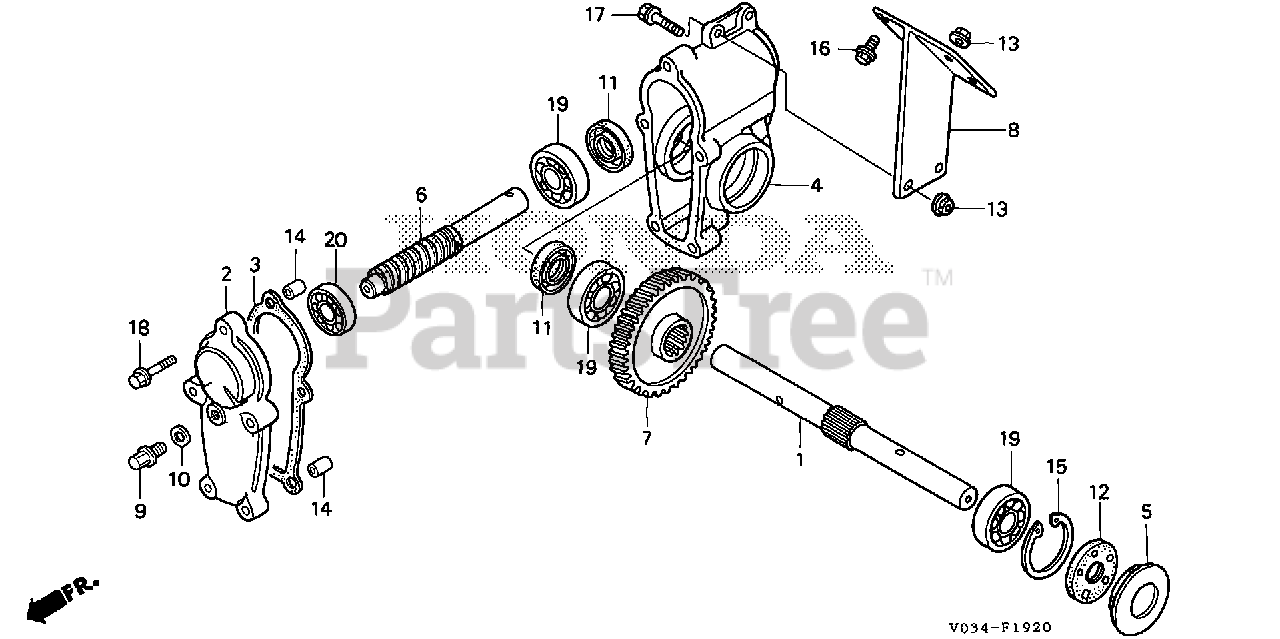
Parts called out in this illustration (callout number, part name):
1	SHAFT, AUGER
2	COVER, AUGER TRANSMISSION
3	GASKET, AUGER TRANSMISSION
4	CASE, AUGER TRANSMISSION
5	CAP, AUGER CASE
6	GEAR, DRIVE
7	GEAR, DRIVEN (55T)
8	BRACKET, AUGER HOUSING
9	BOLT, DRAIN PLUG
10	WASHER, DRAIN PLUG (10.2MM)
11	OIL SEAL (20X32X7)
12	OIL SEAL (20X42X8)
13	NUT, FLANGE (8MM)
14	PIN, DOWEL (8X14)
15	CIRCLIP (INNER) (42MM)
16	BOLT, FLANGE (8X14)
17	BOLT, FLANGE (8X25)
18	BOLT, FLANGE (6X32)
19	BEARING, RADIAL BALL (6004)
20	BEARING, RADIAL BALL (6202)
